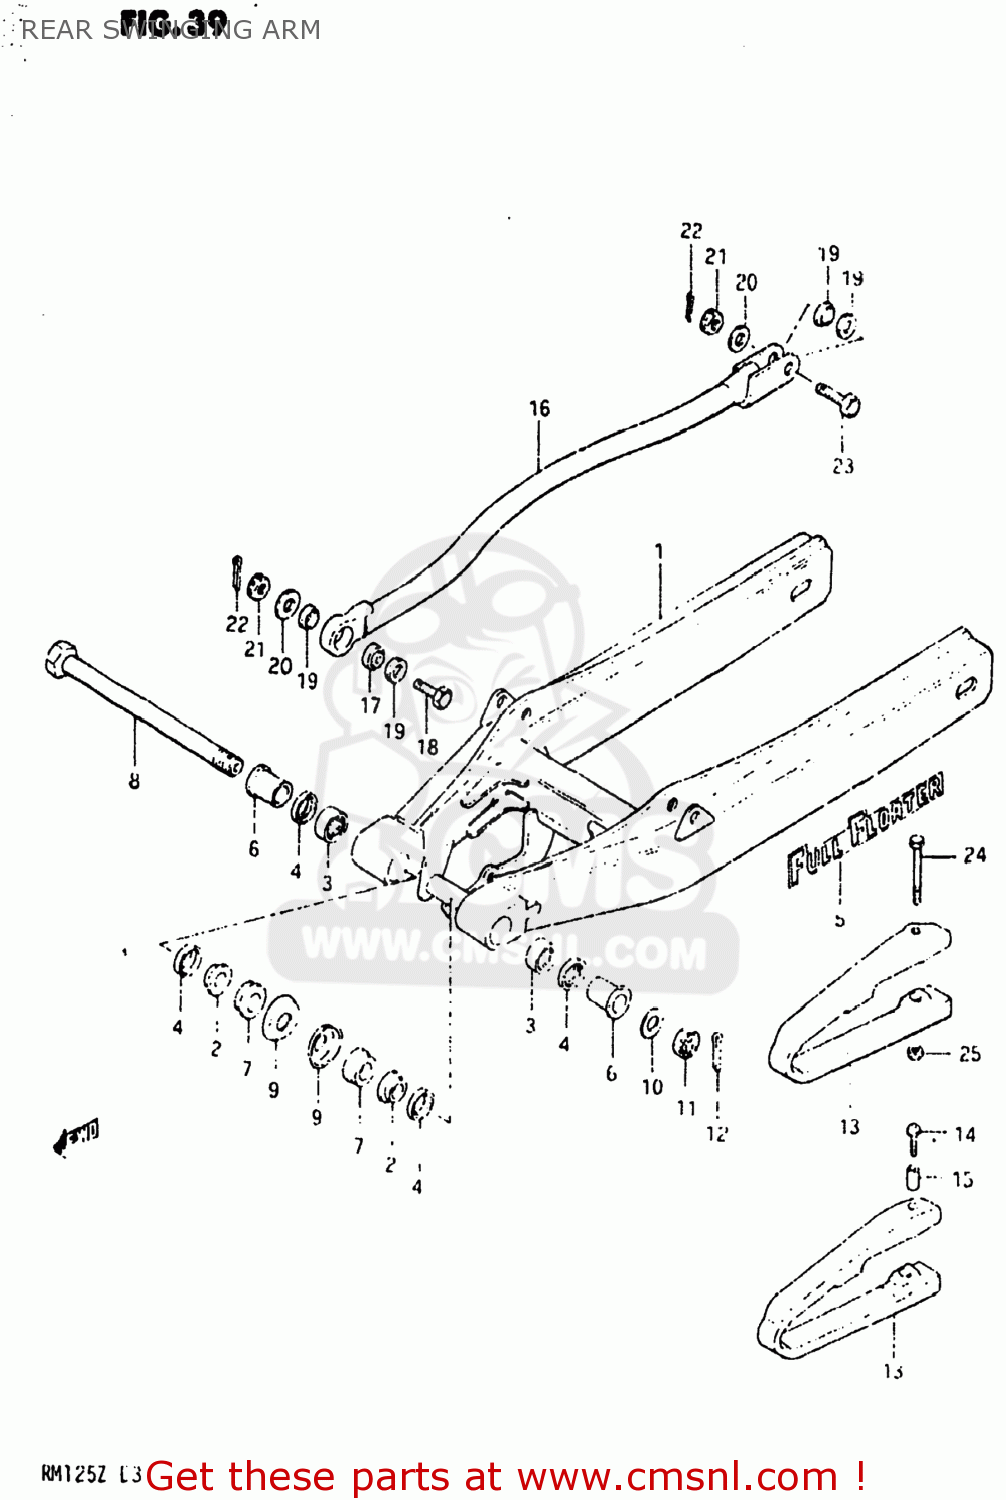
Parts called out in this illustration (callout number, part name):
1	SWING ARM ASSEMBLY,REAR
2	BUSH,RR SWINGINGARM PIVOT
3	BEARING(20X27X20)
4	OIL SEAL
5	EMBLEM,SWING ARM
6	SPACER,RR SWGARM PIVOT
7	SPACER,RR SWGARM PIVOT INNER
8	SHAFT,RR SWINGINGARM PIVOT
9	COVER,RR SWGARM DUST SEAL
10	WASHER
11	NUT 14MM
12	COTTER PIN
13	BUFFER,CHAIN TOUCH DEFLECTOR
14	SCREW,CHAIN TOUCH DEFEND
15	SPACER (5.5X8X4)
16	LINK,REAR TORQUE
17	SPHERICAL BEARING,TORQUE
18	BOLT 8X28
19	20
20	WASHER
21	NUT 8MM
22	PIN 20X20
23	BOLT 8X29.5
24	BOLT
25	NUT
